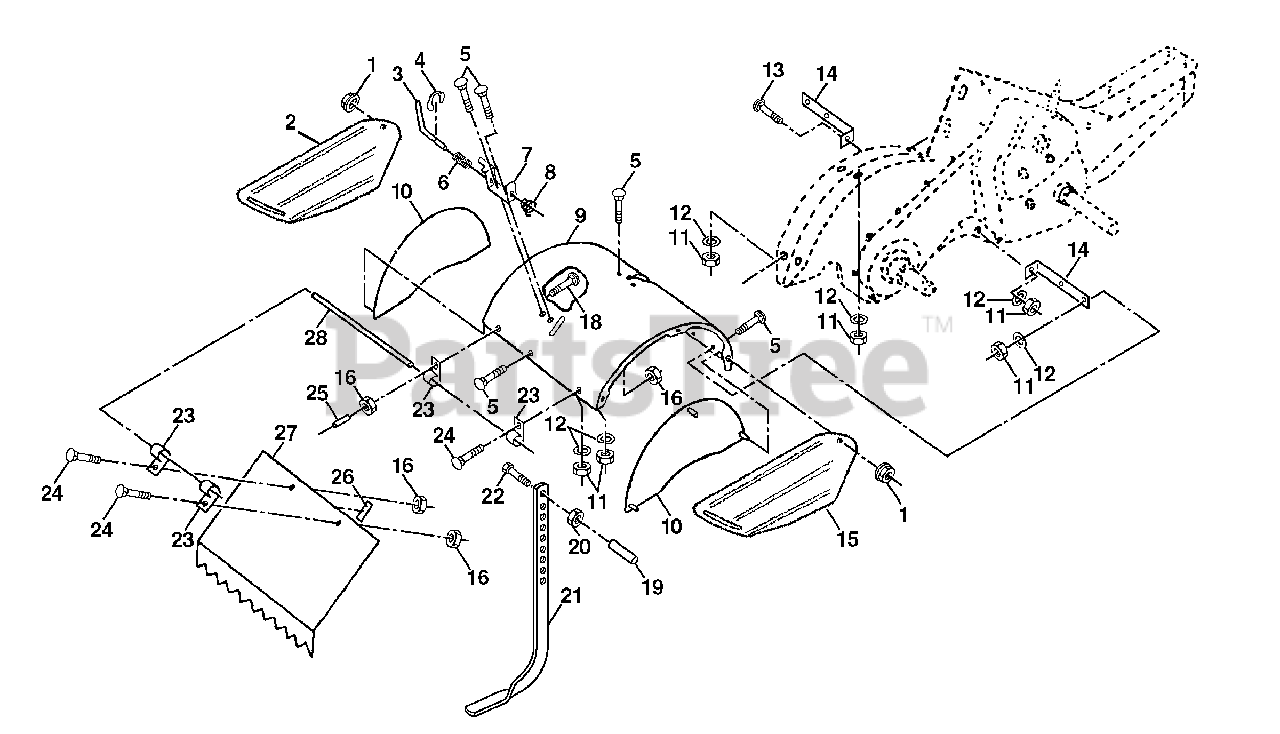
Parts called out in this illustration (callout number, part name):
1	Nut, Flange 5/16-18
2	Shield, Side, Outer L. H.
3	Pin, Stake, Depth
4	Ring, Klip
5	Bolt, Carriage 5/16-18 x 3/4 Gr. 5
7	Bracket, Latch
8	Spring, Depth Stake
9	Shield, Tine
10	Bolt, Carriage 5/16-18 UNC x 1
11	Nut, Hex 5/16-18
12	Washer, Lock 5/16
13	Bolt, Carriage 5/16-18 x 1-1/4
14	Bracket, Shield Tine
15	Shield, Side, Outer R.H.
16	Nut, Keps Hex 1/4-20
18	Bolt, Carriage 1/4-20 x 1-1/4 Gr. 5
20	Nut, Hex 3/8-16
21	Stake, Depth
22	Bolt, Hex 3/8-16 x 2
24	Bolt, Carriage 1/4-20 x 1/2 Gr. 5
25	Cap, Vinyl
26	Pad, Idler
27	Shield, Leveling
28	Pin, Hinge
29	Shield, Side
30	Locknut, Flange 5/16-18
